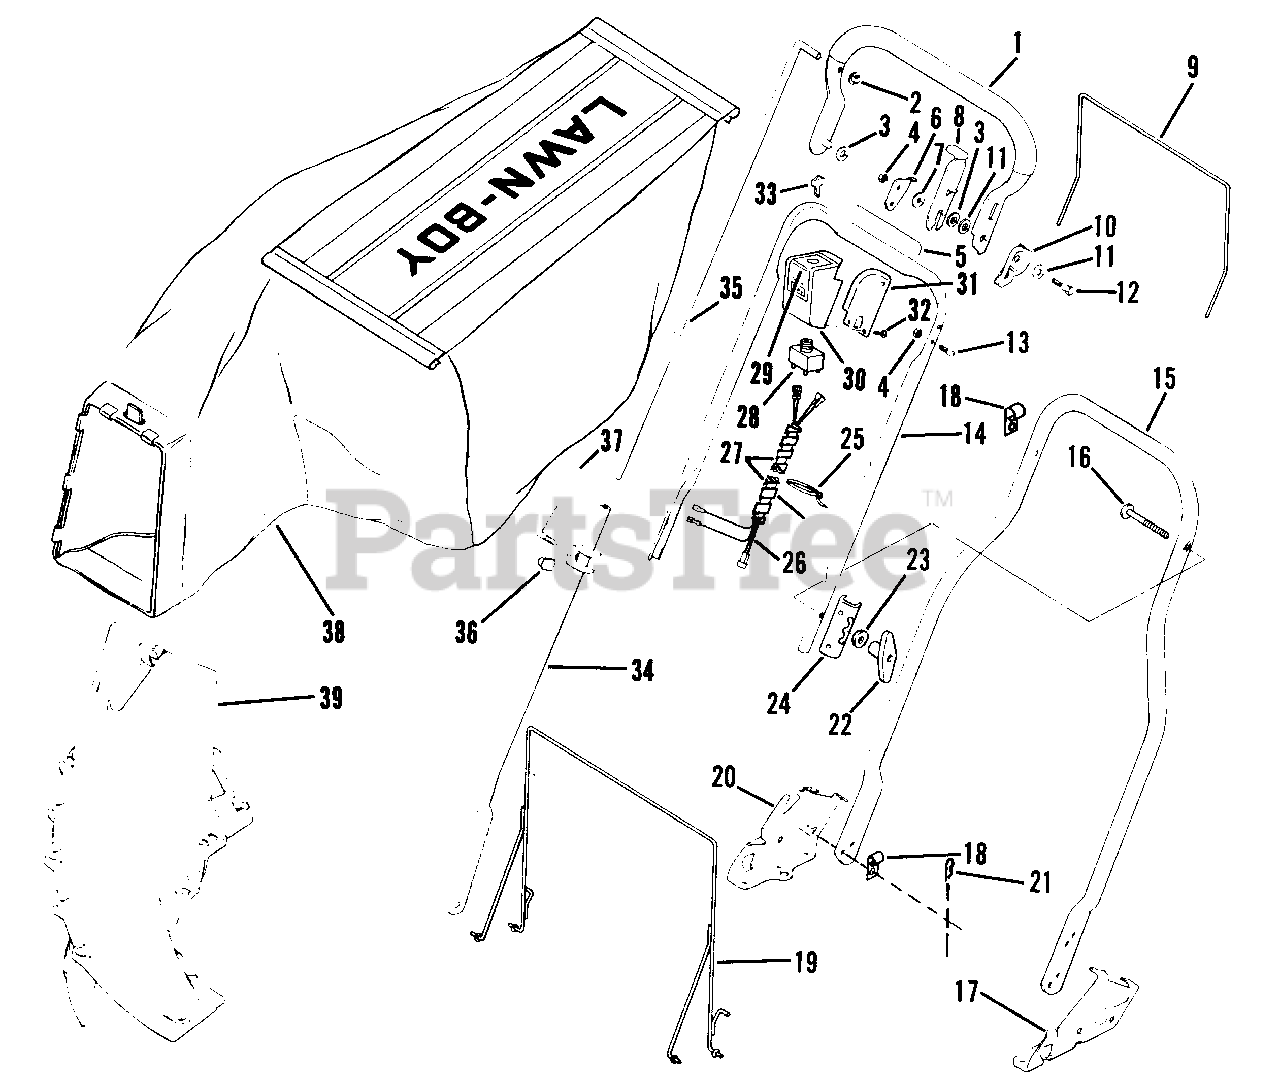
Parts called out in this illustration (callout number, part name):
1	Handle & Grip Assembly
2	Palnut
3	Washer
4	Nut-Lock
5	Decal
6	Stop-Handle
7	Washer
8	Lever-Lockout
9	Hanger-Rear
10	Guard-Lever
11	Washer
12	Bolt-Shoulder
13	Screw-Stop
14	Handle-Center
15	Handle Section-Bottom
16	Screw
17	Bracket-Handle-L.H.
18	Clamp
19	Hanger Assembly-Front
20	Bracket-Handle-R.H.
21	Hair Pin
22	Knob
23	Washer-Curved
24	Bracket-Rear Hanger
25	Cable Tie
26	Wire Harness Assembly Switch
27	Spiral Tubing
28	Key Switch
29	Decal-Switch
30	Housing-Switch
31	Retaining Plate-Switch Housing
32	Screw
33	Key-Switch
34	Control Lever Assembly
35	Control Rod
36	Nut
37	Screw
38	Bag & Deflector Assembly
39	Chute Assembly
